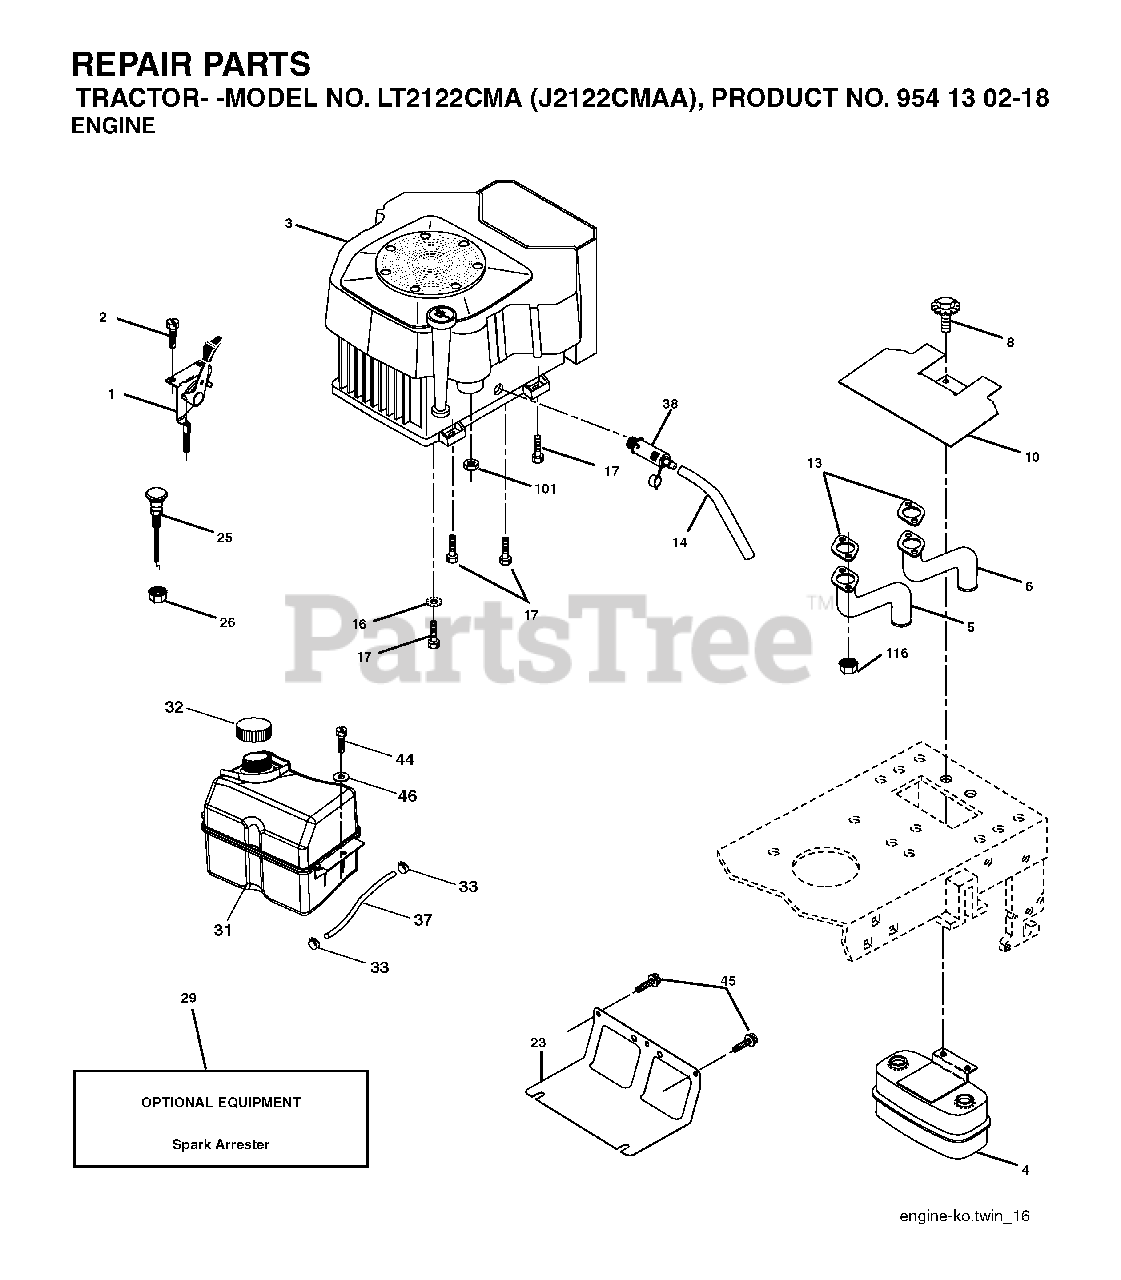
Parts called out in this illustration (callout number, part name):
1	CONTROL.THROTTLE.KAWA
2	SCREW
4	MUFFLER.TWIN.CYL.LOW.TONE
5	PIPE-EXHAUST LH
6	PIPE-EXHAUST RH
8	BOLT, 5/16-18 X 1 3/4
10	RP SHIELD HEAT MUFFLER
13	GASKET.EXHAUST.KOHL.CV18-CV26
14	TUBE, DRAIN OIL ASM.
16	LOCKWASHER
23	SHEILD.BROWNING.DBR.GUARD
25	CHOKE CONTROL
26	NUT KEPS 3/8 - 24 UNF
29	ARRESTER SPARK (OPTIONAL)
31	TANK FUEL
32	FUEL CAP
33	HOSE CLAMP
37	LINE.FUEL.20
38	PLUG DRAIN OIL EASY
44	SCREW HEXWSHR 1/4-20X3/4
45	SCREW, 3/8-16X3/4
101	FLANGE NUT
116	NUT.HEX.FLANGE.TOPLOCK
